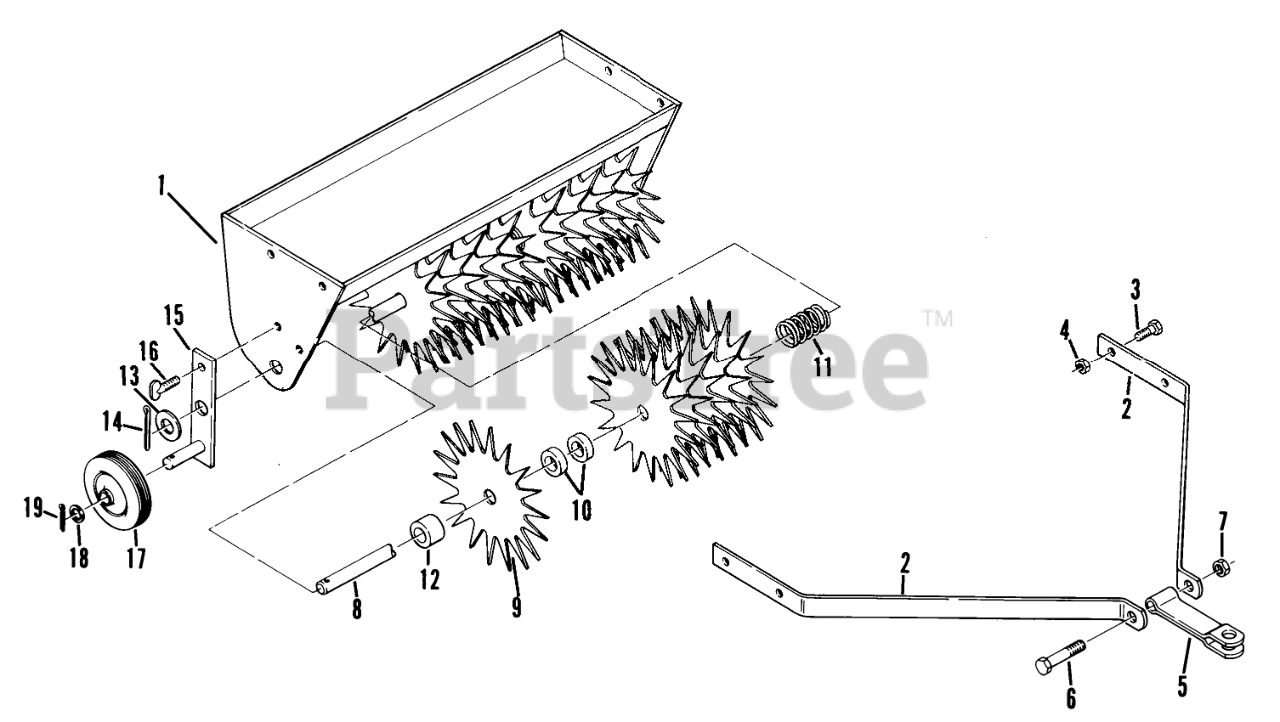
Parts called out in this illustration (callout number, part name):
1	Weight Tray Assembly
2	Side Bar
3	Bolt
4	Nut
5	Hitch Assembly
6	Bolt 1/2-13 x 3 1/2
7	Nut
9	Spike
10	Cup Spacer
11	Spring
12	BUSHING
13	Washer
14	Cotter Pin
14	DECAL-WHEEL HORSE
15	R.H. Wheel Holder
15	L.H. Wheel Holder
16	Thumb Screw
17	Wheel
18	Washer
19	Cotter Pin
